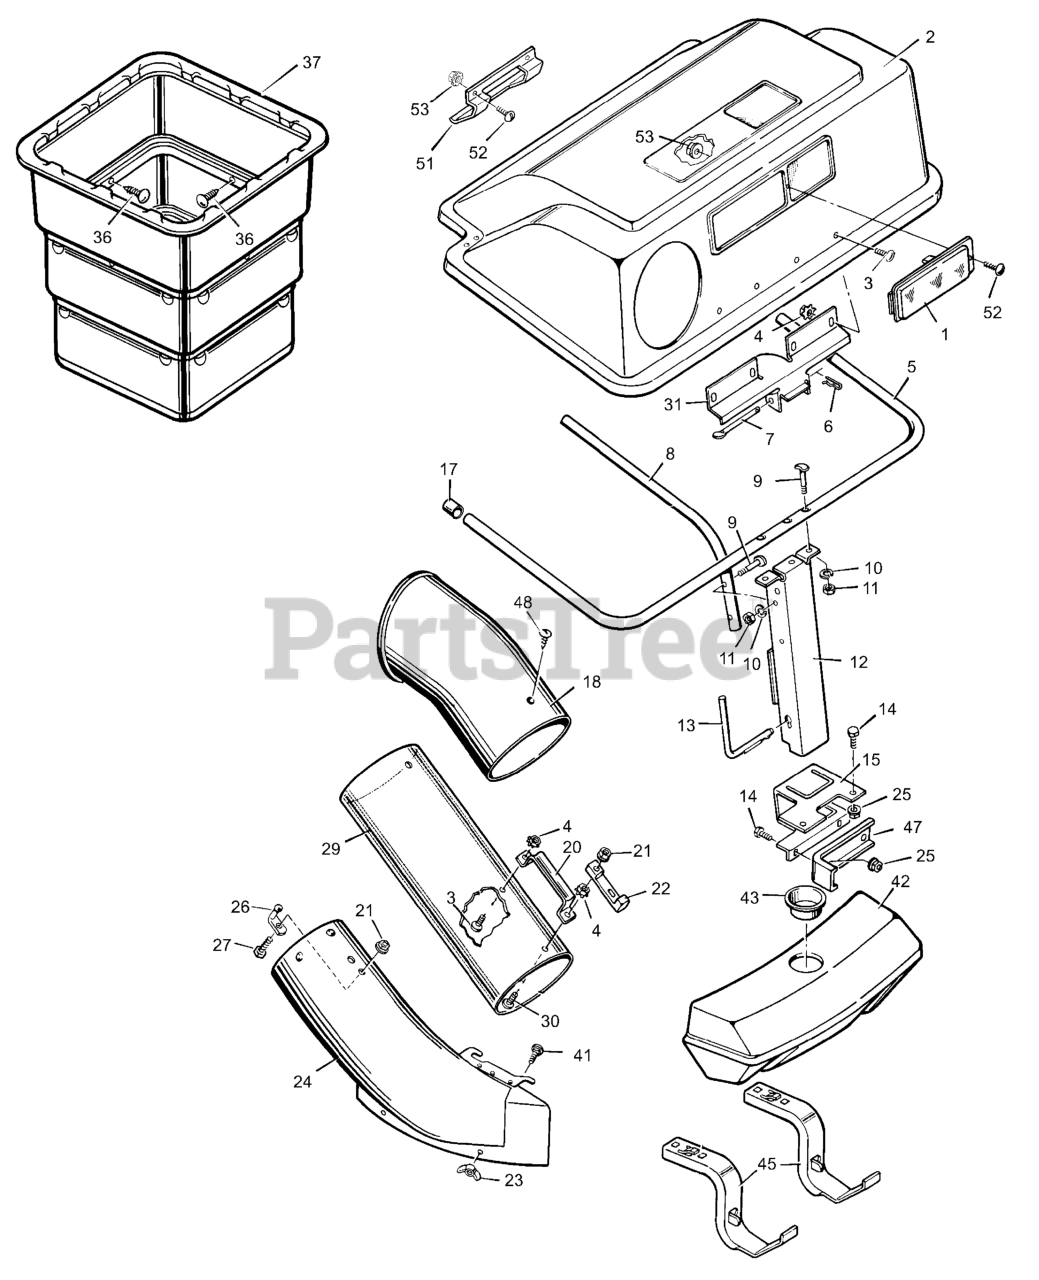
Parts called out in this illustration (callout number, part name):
4	Locknut
6	Pin, Hair
7	Pin, Hinge
8	Tube, Center
9	Bolt, Special
10	Lockwasher
11	Nut, Hex
12	Channel Assembly
13	Pin, Channel
14	Bolt, Hex
15	Hitch Assembly
17	Cap, End
20	HANDLE, Connect Tube
21	Locknut, Flange
22	Latch, Rubber
23	Wingnut
24	Tube, Chute Extension
25	Locknut
26	Pin, Latch
27	Bolt, Carriage
29	Tube, Connector
31	Hinge, Cover
36	Fastener, Plastic
37	Containers
41	Bolt, Carriage
42	Shell, Front Weight
43	Plug, Front Weight
45	Bracket, Front Weight
47	Bracket, Support
51	Handle, Plastic
53	Nut, Hex
